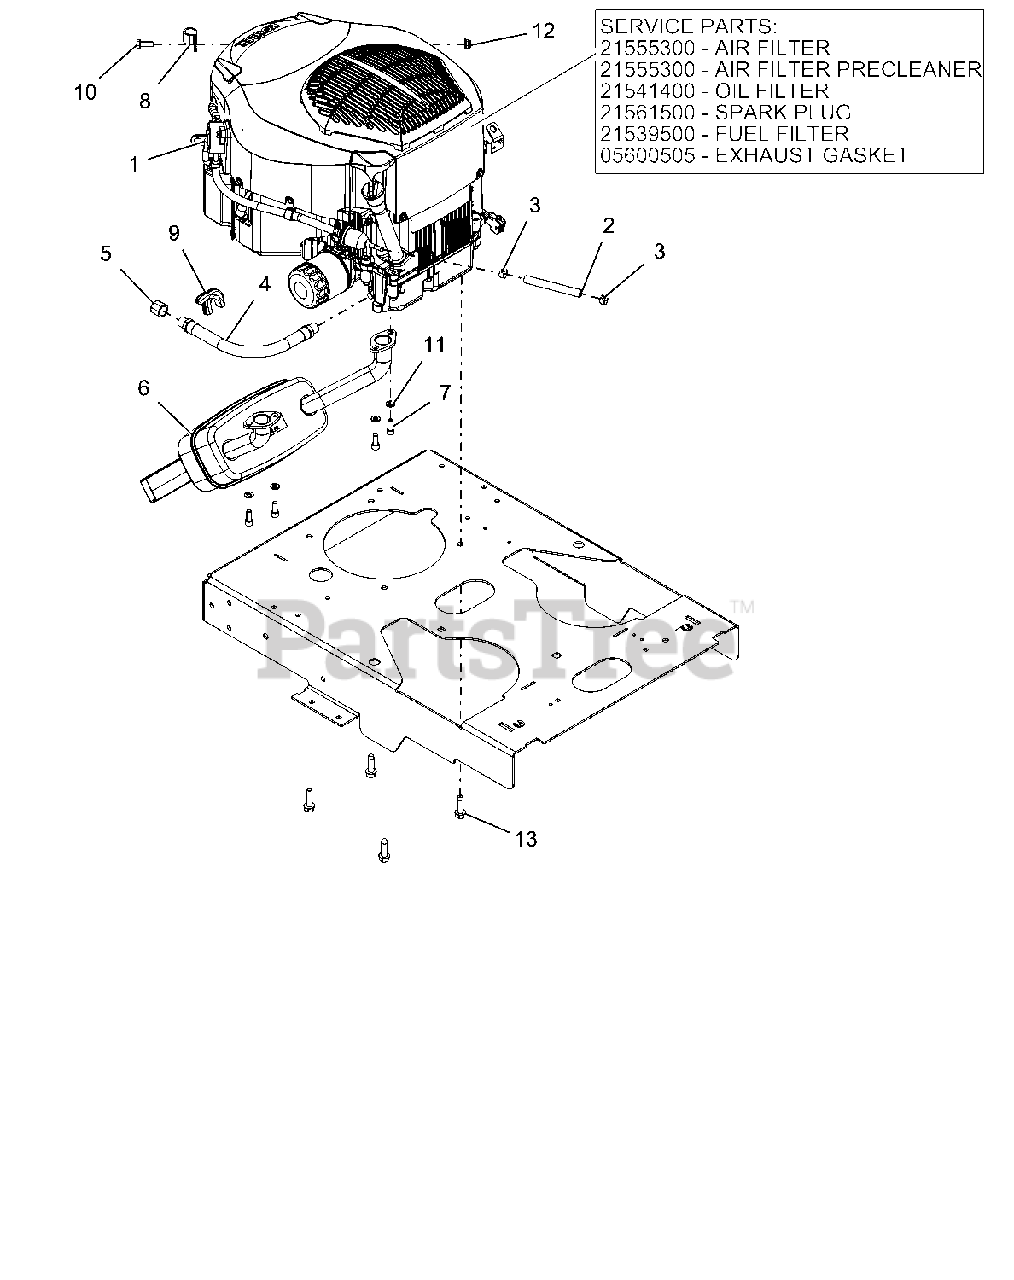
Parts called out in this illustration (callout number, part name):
1	AIR FILTER
1	AIR FILTER PRE-CLEANER
1	OIL FILTER
1	SPARK PLUG
1	FUEL FILTER
1	EXHAUST GASKET
1	ENGINE, KOHLER TWIN - 25HP
2	.25 LOW-PERM GAS HOSE 21.50" LG - TANK TO ENGINE
3	CLAMP, FUEL LINE
4	HOSE, HYD .38-11-OK M6N0-M6N0
5	PIPE, CAP 3/8 NPT FEMALE
6	MUFFLER, KOHLER
7	SCR, CAP SOCKET HEAD
8	CLAMP, CUSHIONED STEEL .75
9	PROTECTOR, OIL DRAIN HOSE
10	BLT-HEX .31-18X.875 GR5 YWZC
11	WSHR-LK .31X.078 REG YWZC
12	NUT-LK-NYL-FLG .31-18 YWZC
13	SCR-TAP .38-16X1.25 HWH TR YZ
